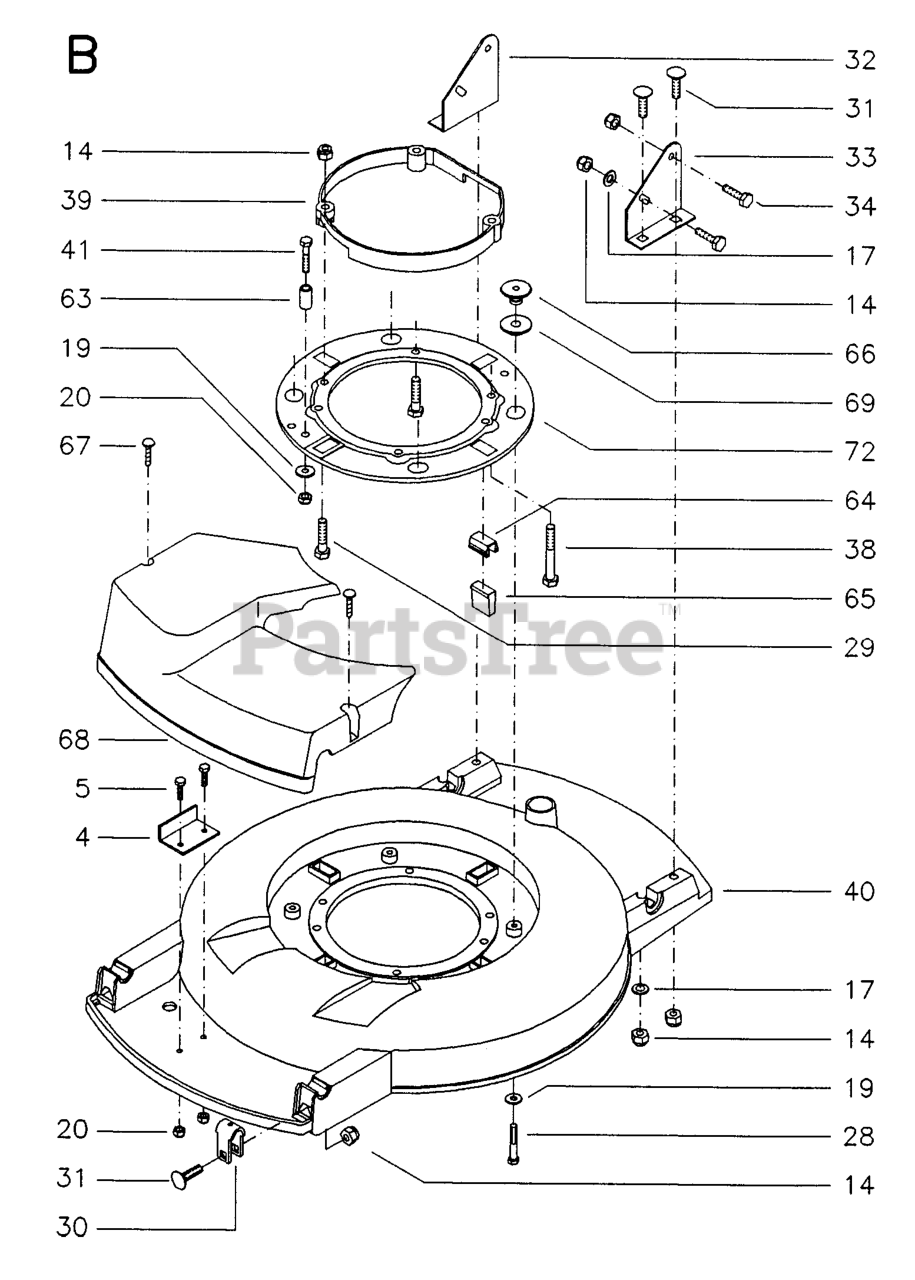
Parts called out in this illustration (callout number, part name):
5	Screw
14	LOCKNUT M8
17	WASHER - 15X7.3X1.6
20	LOCKNUT M6
30	BEARING HOLDER
32	HANDLE BRACKET
33	HANDLE BRACKET
34	BOLT - M8X16
41	BOLT FLANGE
